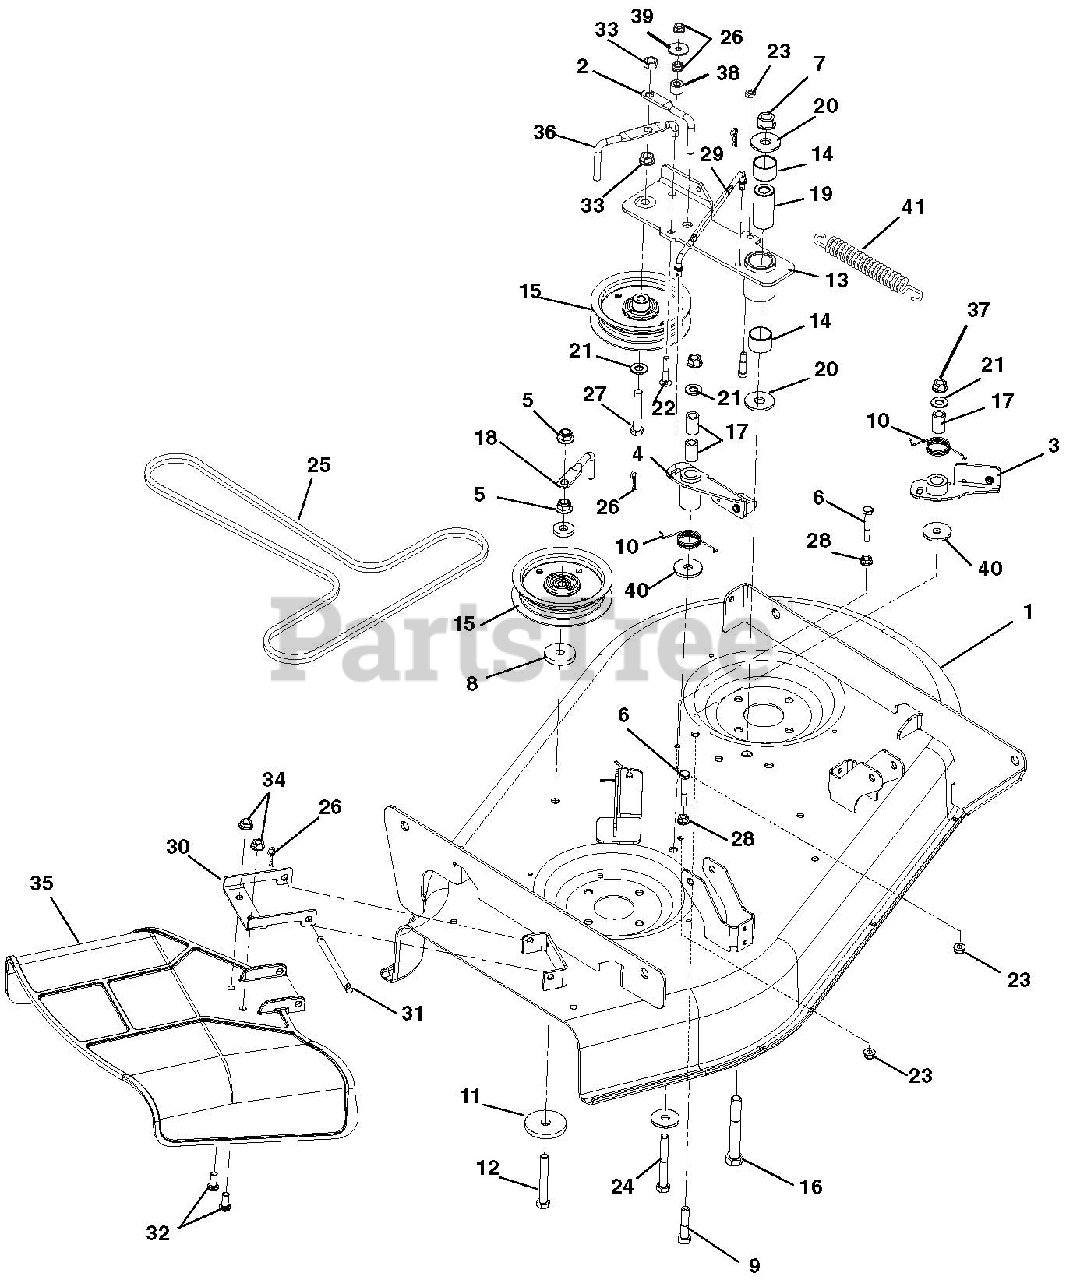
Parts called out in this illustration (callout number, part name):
1	WMT-34" DECK
2	WIREFORM-BELT FINGER
3	ASSY-BRAKE ARM LH
4	ASSY-BRAKE ARM RH
5	@NUT-LK-NYL-FLG .38-16 YWZC
6	@BLT-HEX .25-20X1.75 GR5 YWZC
7	@NUT-LK-TOP-FLG .50-13 YWZC
8	WSHR,FLT STL.406X1.50X.245YWZC
9	@BLT-HEX .38-16X1.75 GR5 YWZC
10	SPRING, TORSION
11	WSHR-FL-STL .469X2.00X.25 YWZC
12	@BLT-HEX .38-16X2.75 GR5 YWZC
13	WMT, IDLER ARM
14	BRG, 1.00 X 1.12 X .75
15	ASM, IDLER 4"
16	@BLT-HEX .50-13X3.50 GR5 YWZC
17	BUSH.,S.391X.622X.950 ST
18	WIREFORM-BELT FINGER
19	BSHG, SPCR .502X.997X2.03 PM
20	WSHR-FL-STL.511X1.441X.125 YWZ
21	@WSHR-FL-STL.406X.812X.065 YWZ
22	@BLT-HEX .25-20X1.00 GR5 YWZC
23	@NUT-LK-NYL-FLG .25-20 YWZC
24	@BLT-HEX .38-16X3.00 GR5 YWZC
25	V-BELT, HA-WRAPPED
26	PIN-HAIR INT .08X.18X1.18 YWZC
27	@BLT-HEX .38-16X2.25 GR5 YWZC
28	@NUT-SPNLK-FLG .25-20 YWZC
29	WIREFORM-LINK, BRAKE
30	CHUTE REINFORCEMENT
31	PIN, 5/16 X 3.88"
32	SCR-SKH .31-18X.75 BTNHD YWZC
33	@NUT-LK-NYL-FLG .38-16 YWZC
34	@NUT-LK-TOP-FLG .31-18 YWZC
35	MOLDED CHUTE, ZOOM
36	WIREFORM, BELT FINGER
37	@NUT-LK-CTR-JAM .375-16 YWZC
38	SPACER .325 X.625 X.455
39	WSHR-FL-STL .281X1.000X.063
40	WSHR-FL-STL .406X1.375X.135 YZ
41	SG-TENS .080X.687X5.16 WLD 28
